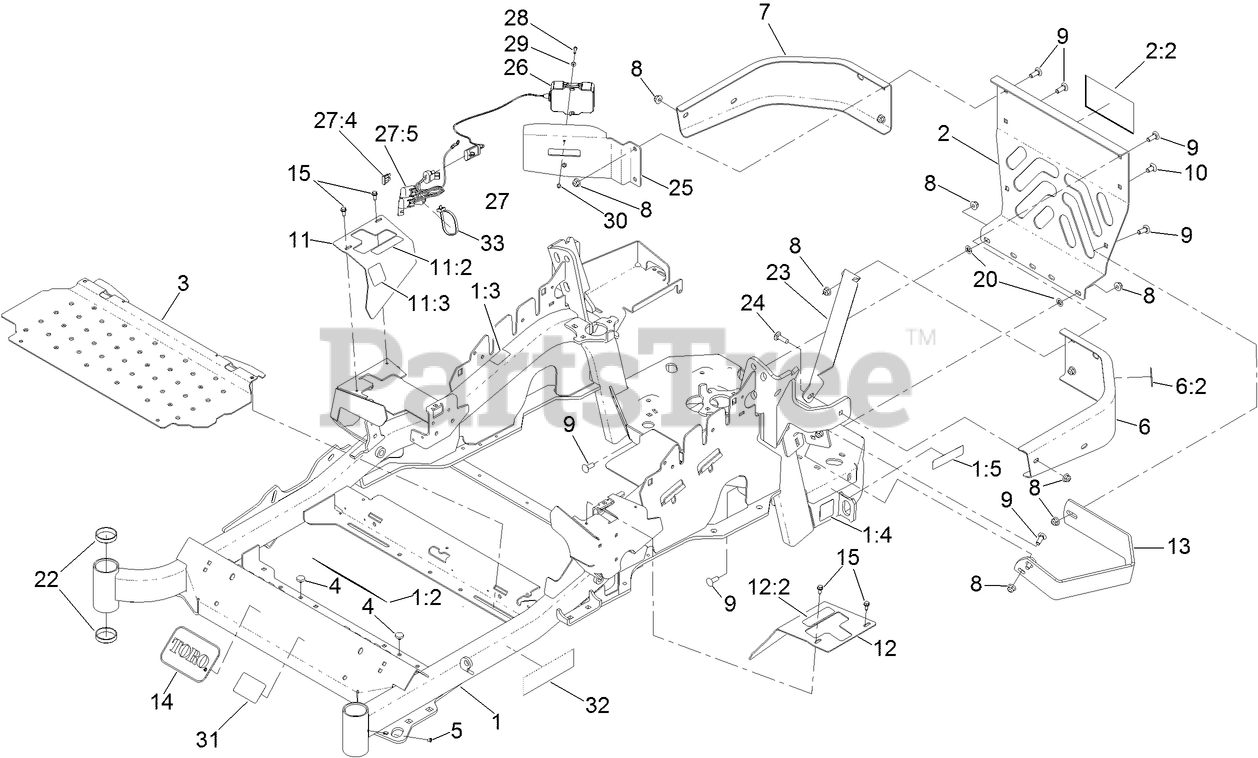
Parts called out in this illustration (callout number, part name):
1	MAINFRAME ASM
1:2	DECAL-DANGER
1:3	DECAL-WARNING
1:4	DECAL-HAZARD, PINCHED FINGER
1:5	DECAL-ARRESTOR, SPARK
2	REAR GUARD ASM
2:2	DECAL
3	FLOORPAN
4	BUMPER
6	LH BUMPER ASM
6:2	DECAL-WARNING
7	BUMPER-RH
8	NUT-HF, NI
9	SCREW-CARR
10	SCREW-CARR
11	RH MOTION CONTROL COVER ASM
11:2	DECAL-CONTROL, MOTION
11:3	DECAL-PARK BRAKE, CE
12	LH MOTION CONTROL COVER ASM
12:2	DECAL-CONTROL, MOTION
13	GUARD-MUFFLER
14	DECAL
15	SCREW-HWH
20	NUT-PUSH
22	CUP-BEARING
24	BOLT-CARR
25	BRACKET [BLACK]
26	GPS ASM
27	HARNESS-WIRE, GPS
27:4	FUSE-MINI BLADE, 5 AMP
27:5	COVER-FUSE, SINGLE
28	SCREW-PPH
29	WASHER-FLAT
30	NUT-LOCK
31	DECAL-CPER0011
32	DECAL-CPER0014
33	TIE-PLASTIC
